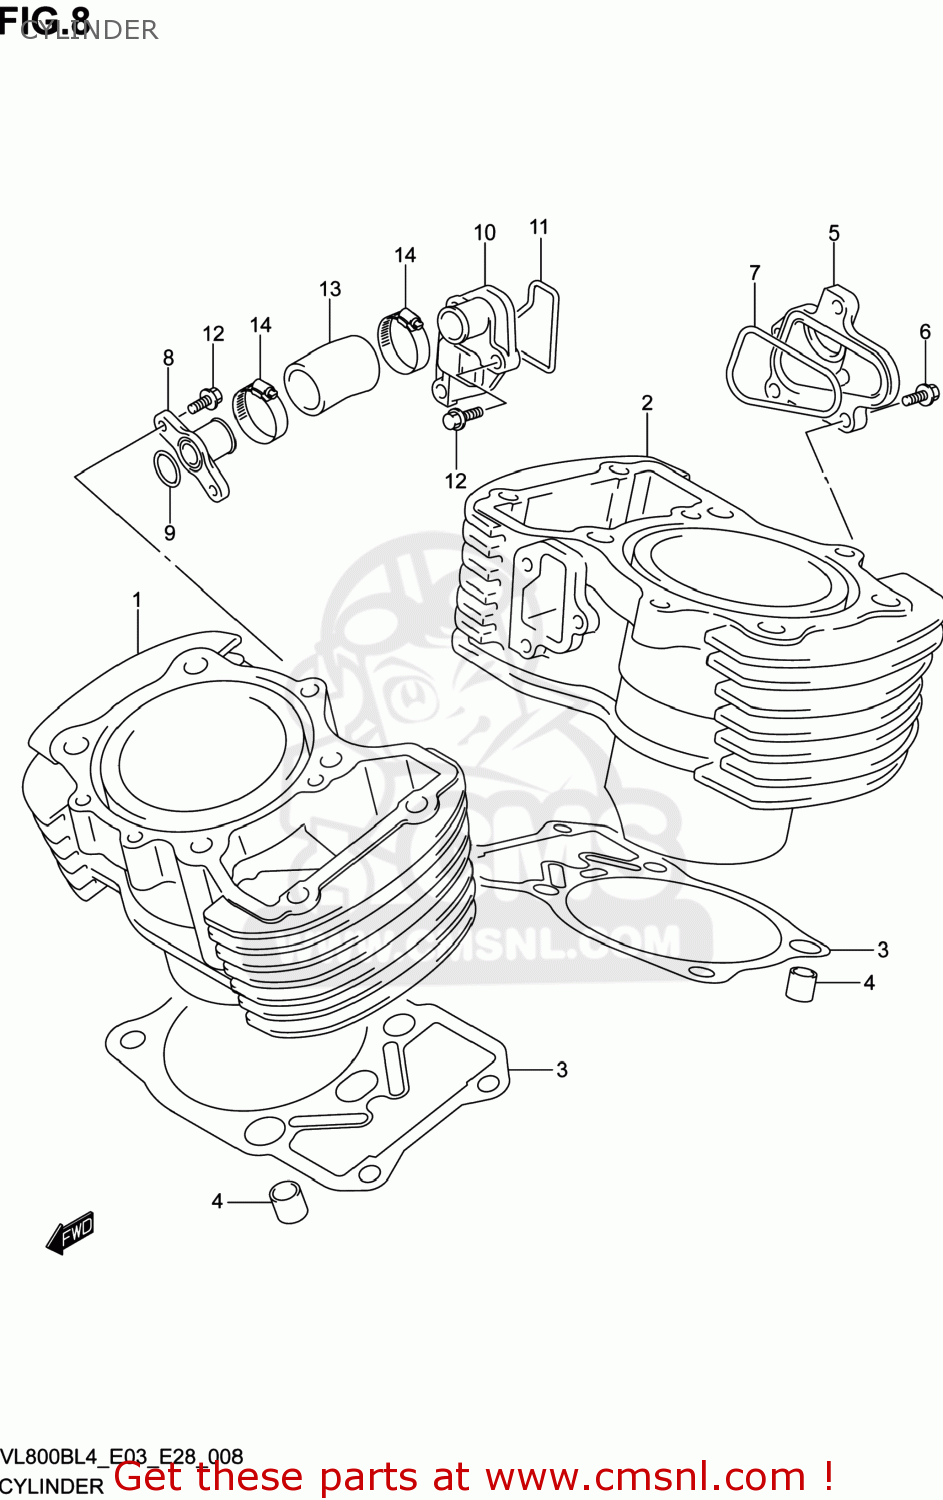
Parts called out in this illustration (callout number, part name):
1	CYLINDER,FR
2	CYLINDER,RR
3	GASKET,CYLINDER (NAS)
4	PIN
5	CONNECTOR,CYLINDER INLET PIPE
6	BOLT
7	O RING,INLET WATER CHAMBER
8	UNION,CYL INLET
9	O RING(D:2.4,ID:15.8)
10	UNION,CYL OUTLET
11	O RING,CYL OUTLET UNION
12	BOLT
13	HOSE,CYLINDER JOINT
14	CLAMP
